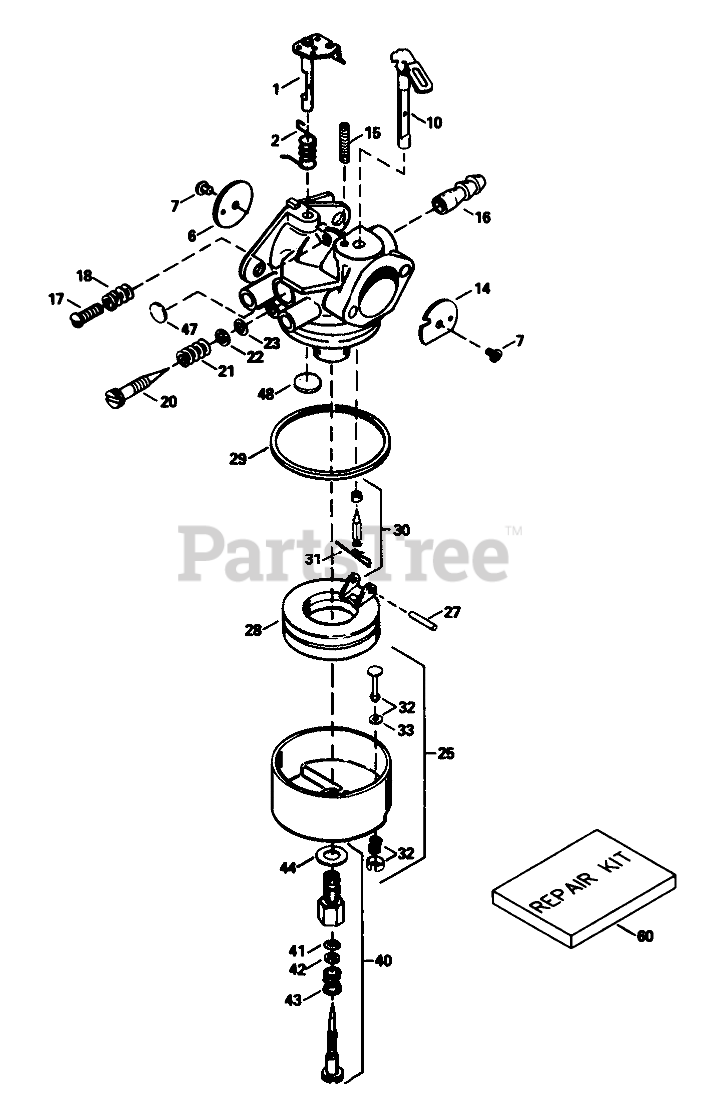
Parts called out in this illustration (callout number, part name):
1	Throttle Shaft and Lever ASM
2	Spring-Return, Throttle
6	Shutter-Throttle
7	Screw-Shutter
10	Choke Shaft and Lever ASM
14	Shutter-Choke
15	Spring-Positioning, Choke
16	Fitting-Fuel
17	Screw-Throttle Crack Screw / Idle Speed
18	Spring-Tension
20	Screw-Idle Mix
21	Spring-Tension
23	"O"Ring
25	Bowl-Float (Incl. Ref. #32, & 33)
27	Shaft-Float
28	Float
29	O Ring-Bowl, Float
30	Inlet Needle-Seat & Spring Clip (Incl. Ref. #31)
31	Clip-Spring
32	Bowl Drain Assembly (Incl. Ref. #33)
33	Gasket-Plunger, Drain
40	Mian Adj. Screw Asm.
41	"O"Ring
44	Washer-Bowl Nut
47	Plug-Welch, Idle Mixture Well
48	Plug-Welch, Atmospheric Vent
60	Kit-Repair
